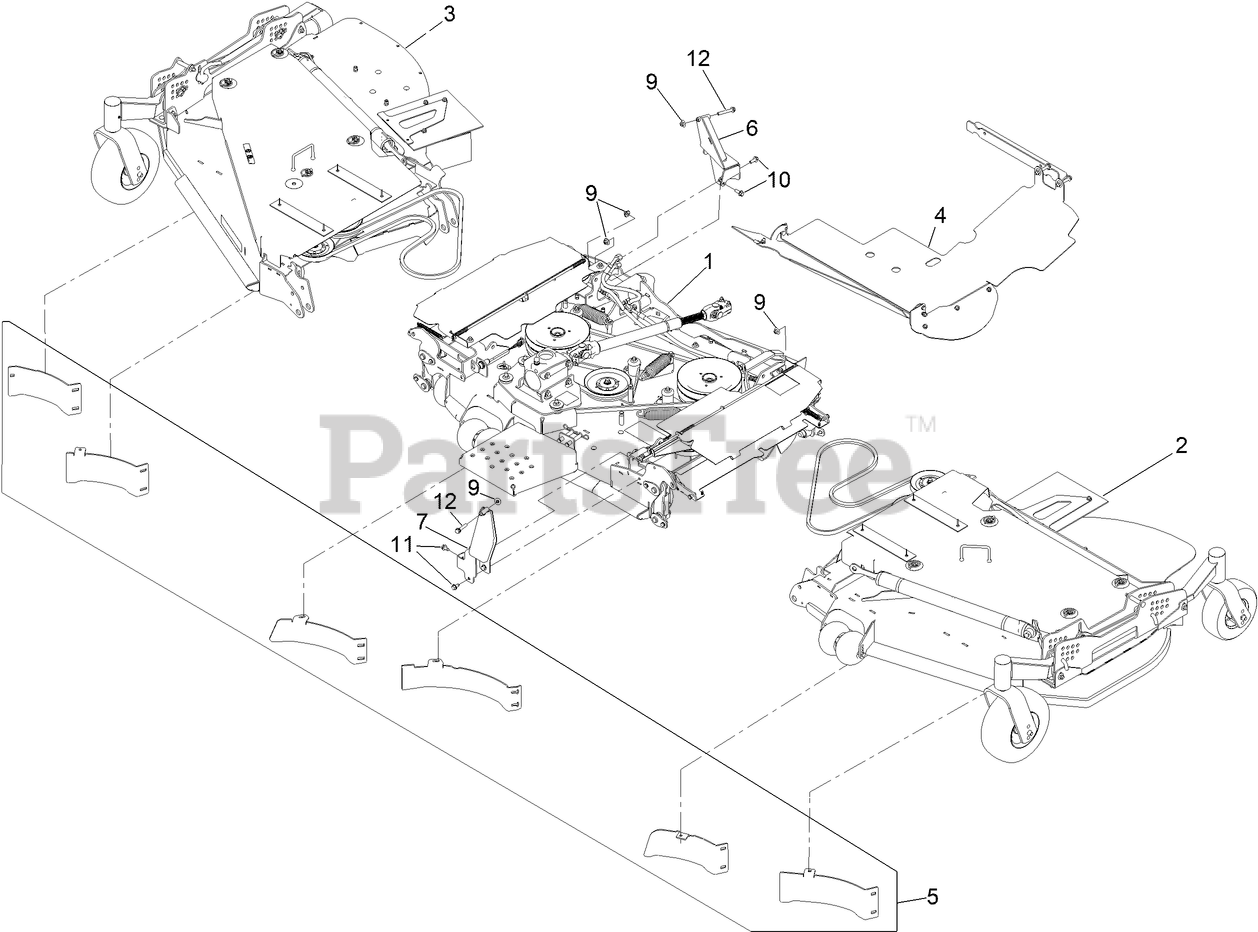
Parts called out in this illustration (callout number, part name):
1	ASM-CENTER DECK
2	ASM-DECK WING LH 144 TORO
3	ASM-DECK, WING RH 144 TORO
4	DISCHARGE-TUNNEL ASM, 144
5	KIT-FINISH CUT BAFFLE 144
6	WELD-RH SPRING MOUNT-UPSTOP
7	BRACKET, LH CENTERDECK-SPRING [BL
9	NUT-FLANGE, NI
10	SCREW-HHF
11	SCREW-HWH
12	SCREW-HHF
